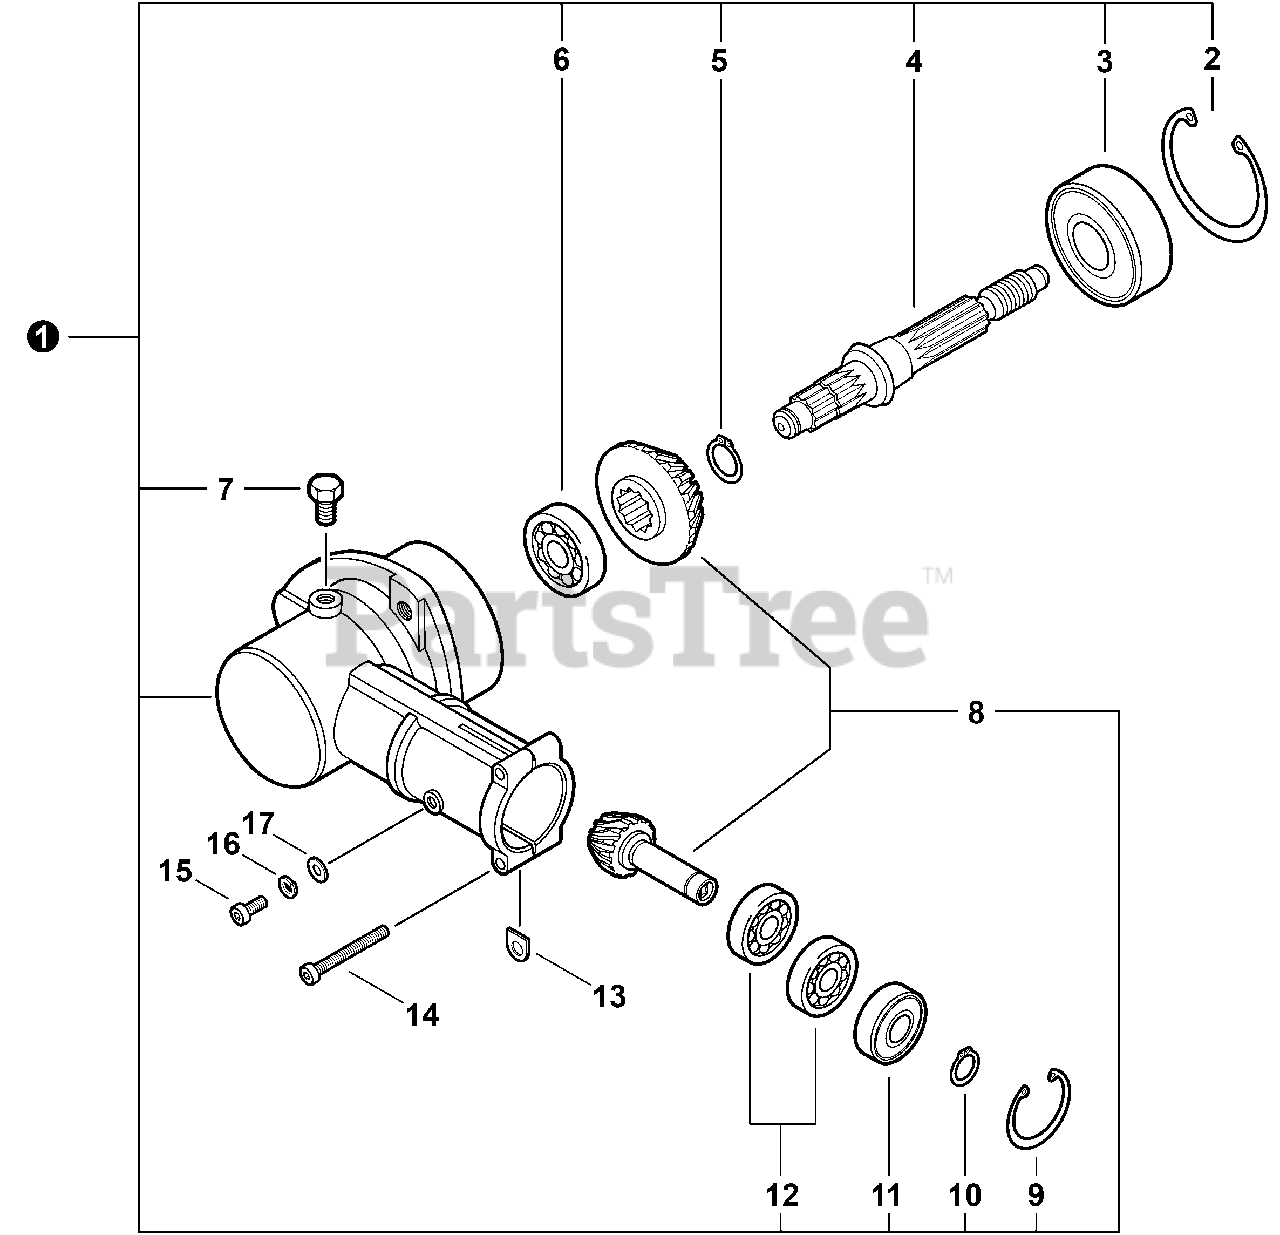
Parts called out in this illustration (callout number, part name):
1	GEAR CASE ASY
2	RING, RETAINING - 42
3	BEARING, BALL 609
4	GEAR, SHAFT
5	RING, RETAINING - 12
6	BEARING, BALL - 629
7	BOLT 8×8
8	GEAR SET
9	RING, RETAINING - 22
10	RING, RETAINING - 10
11	BEARING, BALL - 6900Z
12	BEARING, BALL - 6900
13	WASHER, SHIM
14	SCREW - 5×25
15	SCREW - 5×12
16	LOCKWASHER - 5
